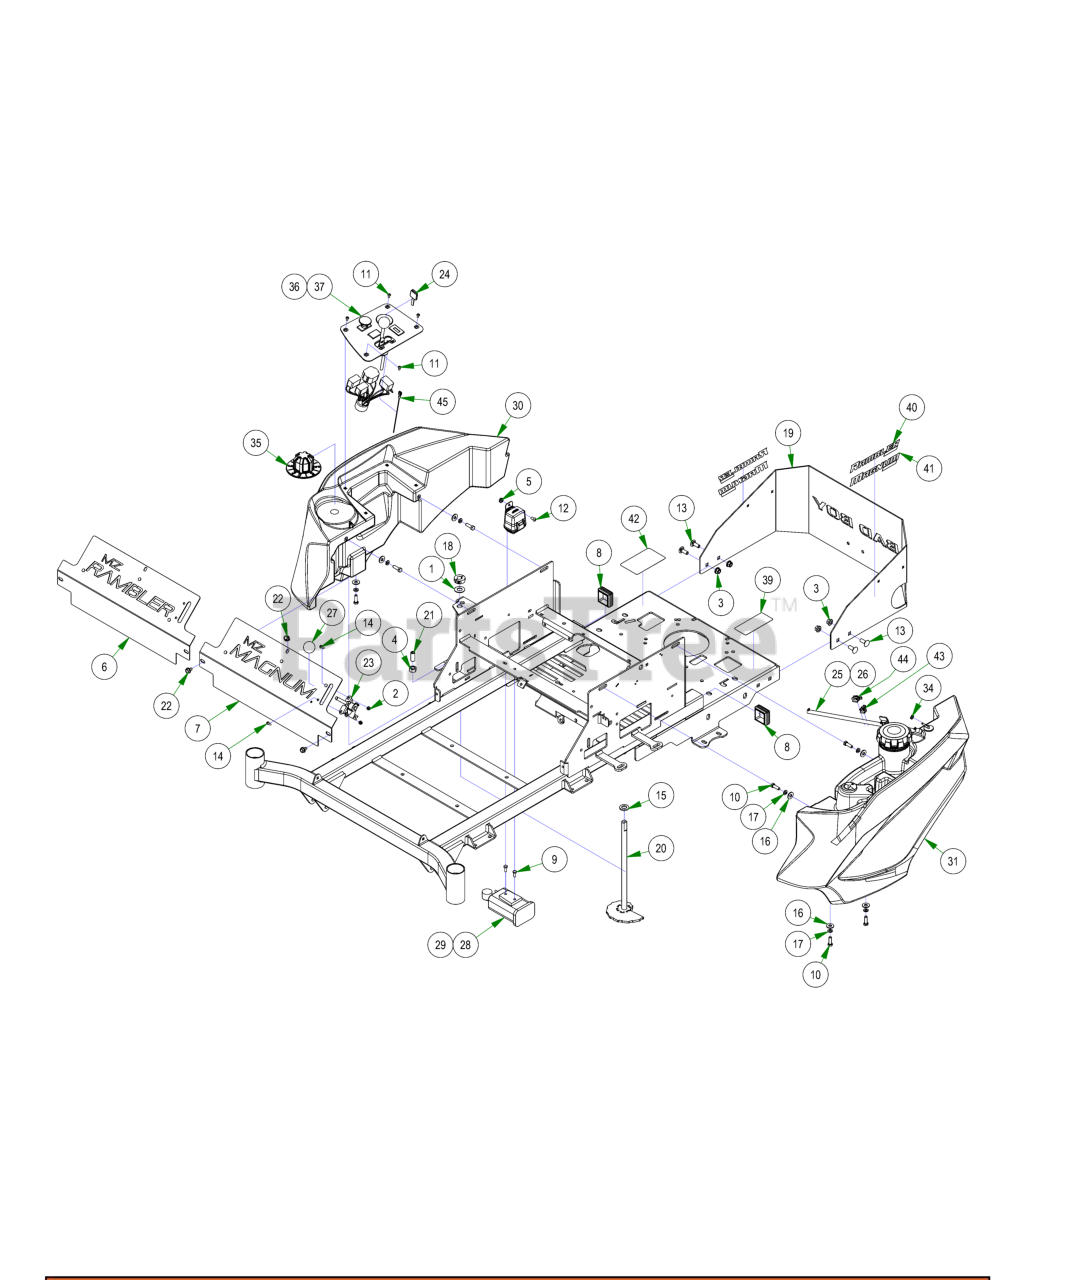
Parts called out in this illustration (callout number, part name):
1	.625 ID x 1.250 OD x .062 THK F/W Nylon
2	10-24 NYLON INSERT LOCKNUT ZINC
3	3/8-16 NYLON INSERT FLANGE LOCKNUT (GR.F) ZINC
4	1/2-13 HEX NUT ZINC
5	1/4-20 HEX SERRATED FLANGE NUT HARD/ZINC
6	2023 MZ Rambler Cooler Cover Assembly
7	2023 MZ Magnum Cooler Cover Assembly
8	2X2 Frame Plug
9	M6-1.0 X 16MM DIN 933 HEX TAP BOLT (CL 8.8) ZINC
10	5/16-18 X 1 HEX CAP SCREW (GR.5) ZINC
11	10-32 X 3/8 BUTTON SOCKET CAP SCREW 18-8 STAINLESS
12	1/4-20 X 1/2 BUTTON SOCKET CAP SCREW 18-8 STAINLESS
13	3/8-16 X 1 CARRIAGE BOLT (GR.5) ZINC
14	10-24 X 5/8 BUTTON SOCKET CAP SCREW 18-8 STAINLESS
15	.635 ID X 1.120 OD X .140 THICK FLAT WASHER NYLON
16	5/16 USS FLAT WASHER (7/8 OD) ZINC
17	5/16 SPLIT LOCKWASHER ZINC
18	5/8" Split Collar
19	2022 MZ Rear Plate
20	Deck Height Dial Rod Assembly
21	Dial Rod Plunger
22	5/16-18 X 1/2 HWH unslot (F) tcs zinc
23	MZ Brake Plate Assembly w/ Brake Cable
24	Ignition Key
25	15" Fuel Line Assembly
26	37" Fuel Line Assembly
27	Throttle Knob
28	MZ Kohler 42" EPA Canister Assembly
29	MZ Kohler EPA Canister Assembly
30	2017 MZ Right Console
31	2017 MZ Left Gas Tank
32	2024 MZ 42-48 Frame
33	2024 MZ-Avenger 54-60 Frame
34	3/16 Vinyl Clamp
35	MZ/ZT Deck Height Dial
36	2023 Rambler Control Panel Assembly
37	2023 Control Panel Assembly
38	2024 Wiring Harness with Clips
39	2024 EPA Build Date Punch Decal
40	Rambler Back Plate Decal
41	Magnum Back Plate Decal
42	Pump Belt Route Decal-Pump Plate
43	Edge Clip With Ziptie
44	Edge Clip With Ziptie
45	2017 MZ/ZT/MAV Tach Wire Assy
